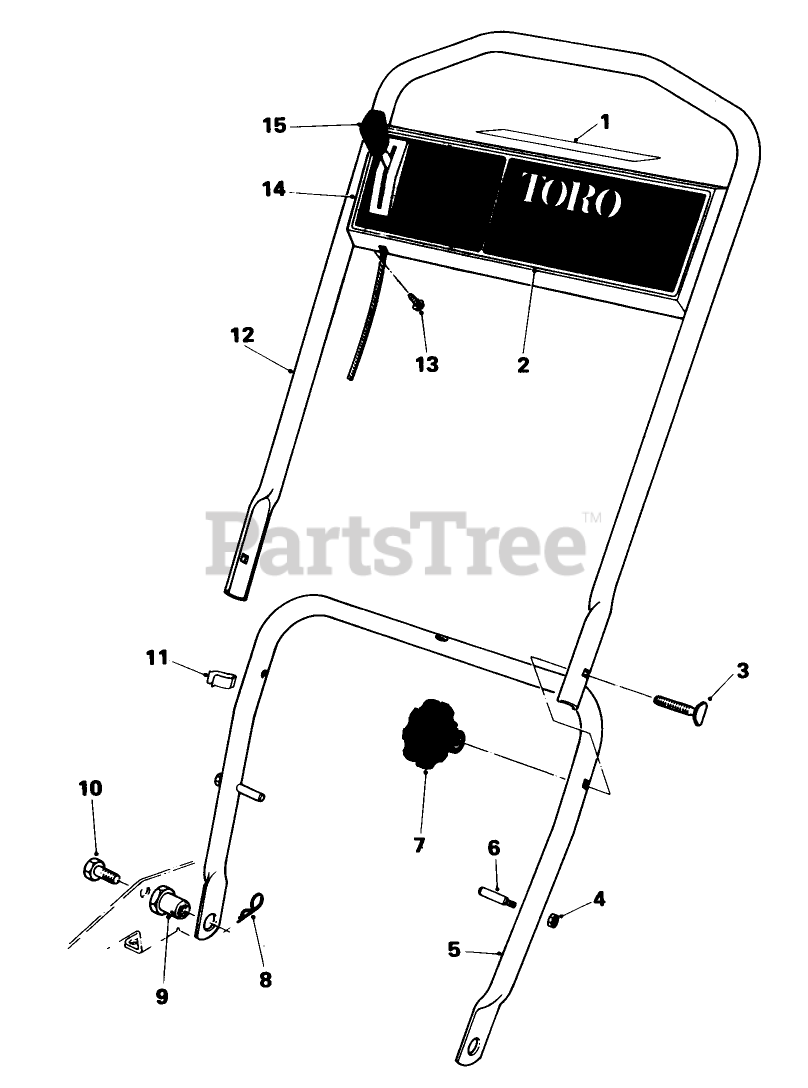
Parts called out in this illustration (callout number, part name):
3	SCREW-HANDLE
6	HANDLE PIN
8	PIN-COTTER, HAIR
9	HANDLE PIVOT NUT
10	SCREW-HH
13	SCREW-HWHTF
